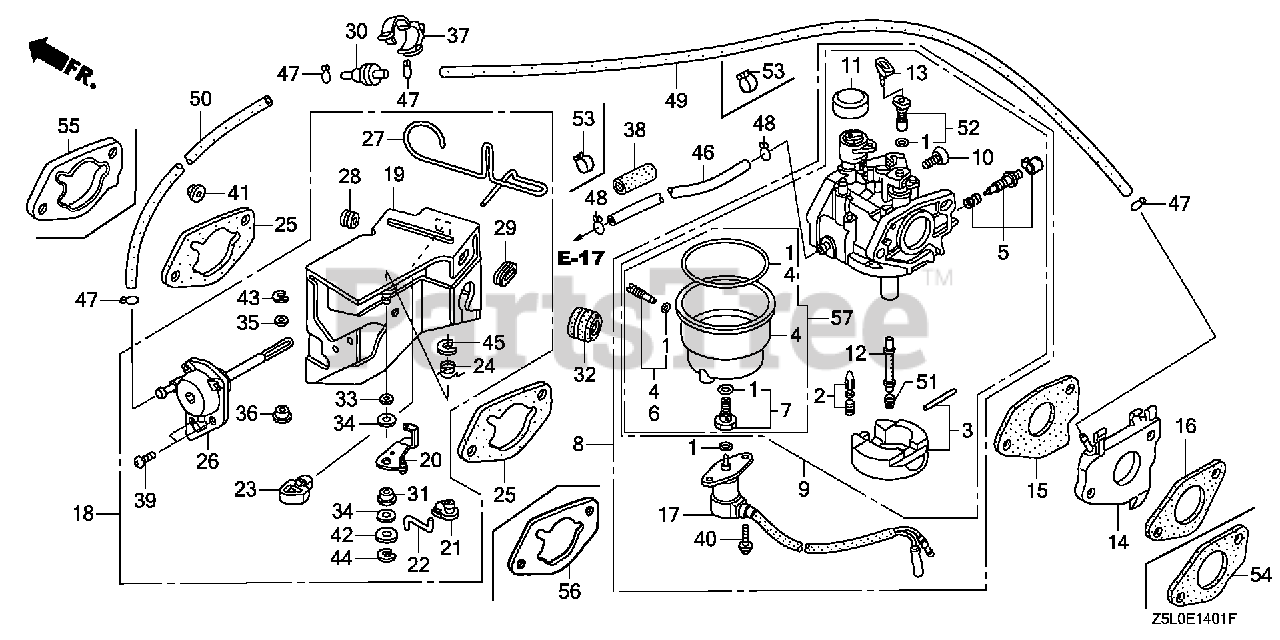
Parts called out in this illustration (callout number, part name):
1	GASKET SET
2	VALVE SET, FLOAT
4	CHAMBER SET, FLOAT
5	SCREW SET, PILOT
6	SCREW SET, DRAIN
8	CARBURETOR ASSY. (BE82V A)
10	SCREW, THROTTLE STOP
11	CAP, CHOKE DUST
12	NOZZLE, MAIN
13	COLLAR, SETTING
14	INSULATOR, CARBURETOR
15	GASKET, CARBURETOR
17	VALVE ASSY., SOLENOID
18	STAY ASSY., MANUAL CHOKE
19	STAY, SOLENOID
20	LEVER, CHOKE
21	JOINT, ROD
22	ROD, CHOKE
23	STOPPER, CHOKE ROD
24	SPRING, MANUAL CHOKE
25	GASKET, AIR CLEANER
26	DIAPHRAGM ASSY.
27	ROD, CHOKE CONTROL
28	GROMMET, CHOKE ROD
29	GUIDE, CHOKE ROD
30	VALVE, DASHPOT CHECK
31	BUSH, ARM PIVOT
32	GROMMET, FENDER
33	WASHER, CHOKE LEVER
34	SEAL, CHOKE LEVER
35	WASHER, THRUST (2.7X8)
36	COLLAR, LEVER
37	CLIP, WIRE HARNESS
39	SCREW, PAN (5X12)
40	SCREW-WASHER (5X12)
41	NUT, FLANGE (6MM)
42	WASHER, PLAIN (5MM)
43	E-RING (2MM)
44	E-RING (4MM)
45	E-RING (7MM)
47	CLIP, TUBE (B7)
49	BULK HOSE, VACUUM (3.5X8000) (3.5X75)
50	BULK HOSE, VACUUM (3.5X8000) (3.5X130)
51	JET, MAIN (#95)
51	JET, MAIN (#98)
51	JET, MAIN (#100)
52	JET SET, PILOT (#38)
54	GASKET, CARBURETOR INSULATOR
